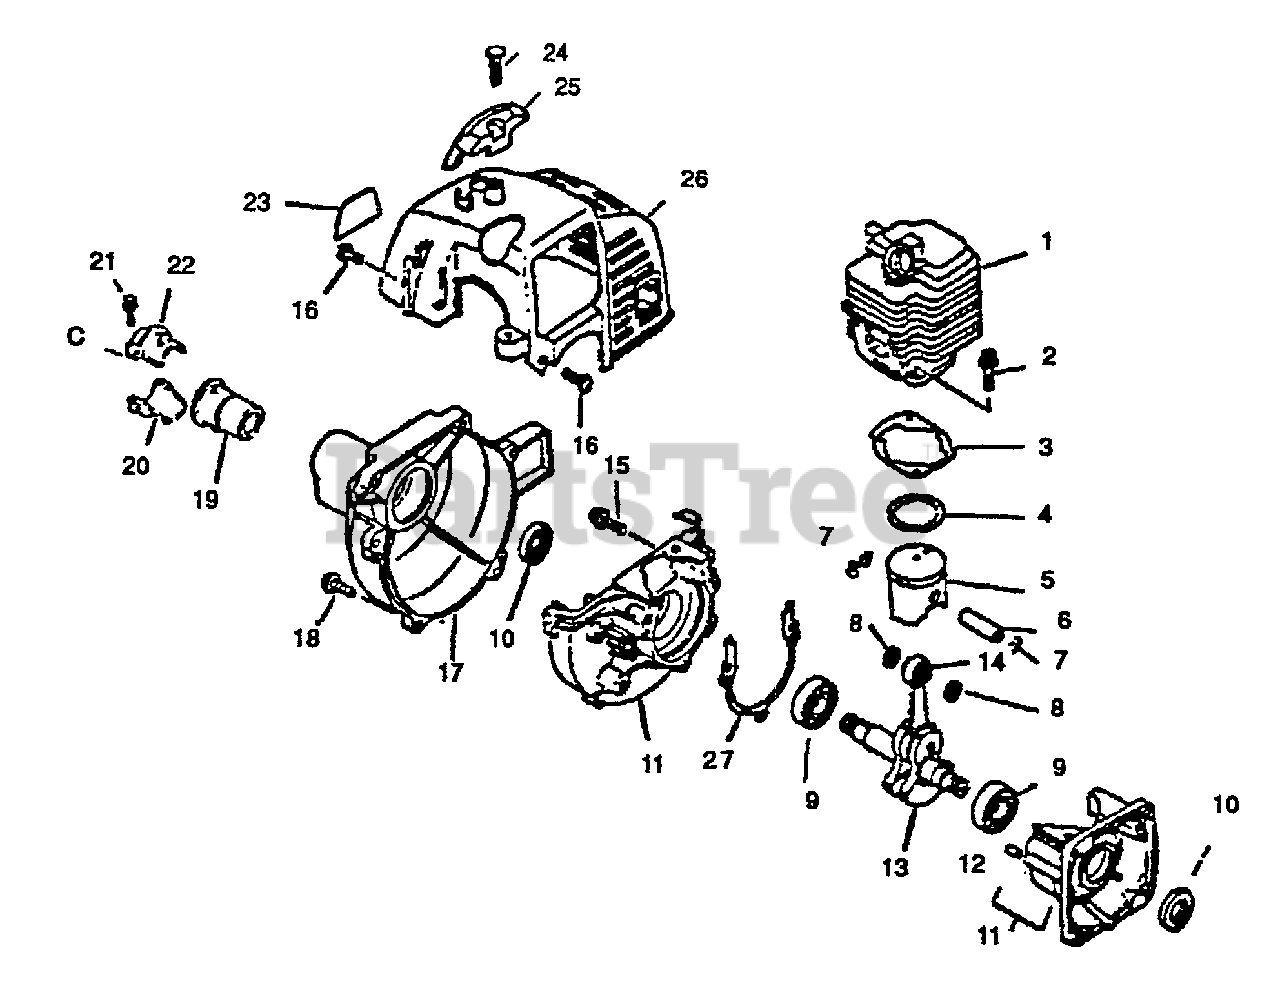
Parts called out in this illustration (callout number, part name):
1	Cylinder
2	Bolt, H. S.
3	Gasket, Cylinder Base
4	Ring, Piston
5	Piston
6	Pin, Piston
7	Circlip, Piston Pin
8	Spacer, Piston Pin
9	Bearing, Ball 6201
10	Oil Seal
11	Crankcase Set
12	Pin, Dowel
13	Crankshaft Asy
14	Bearing, Needle
15	Screw 5X28
16	Screw 4X12
17	Cover, Fan
18	Screw 4X16
21	Bolt 5X25
23	Label, Model
24	Screw 5X16
25	Guard, Top
26	Cover, Cylinder
27	Gasket, Crankcase
